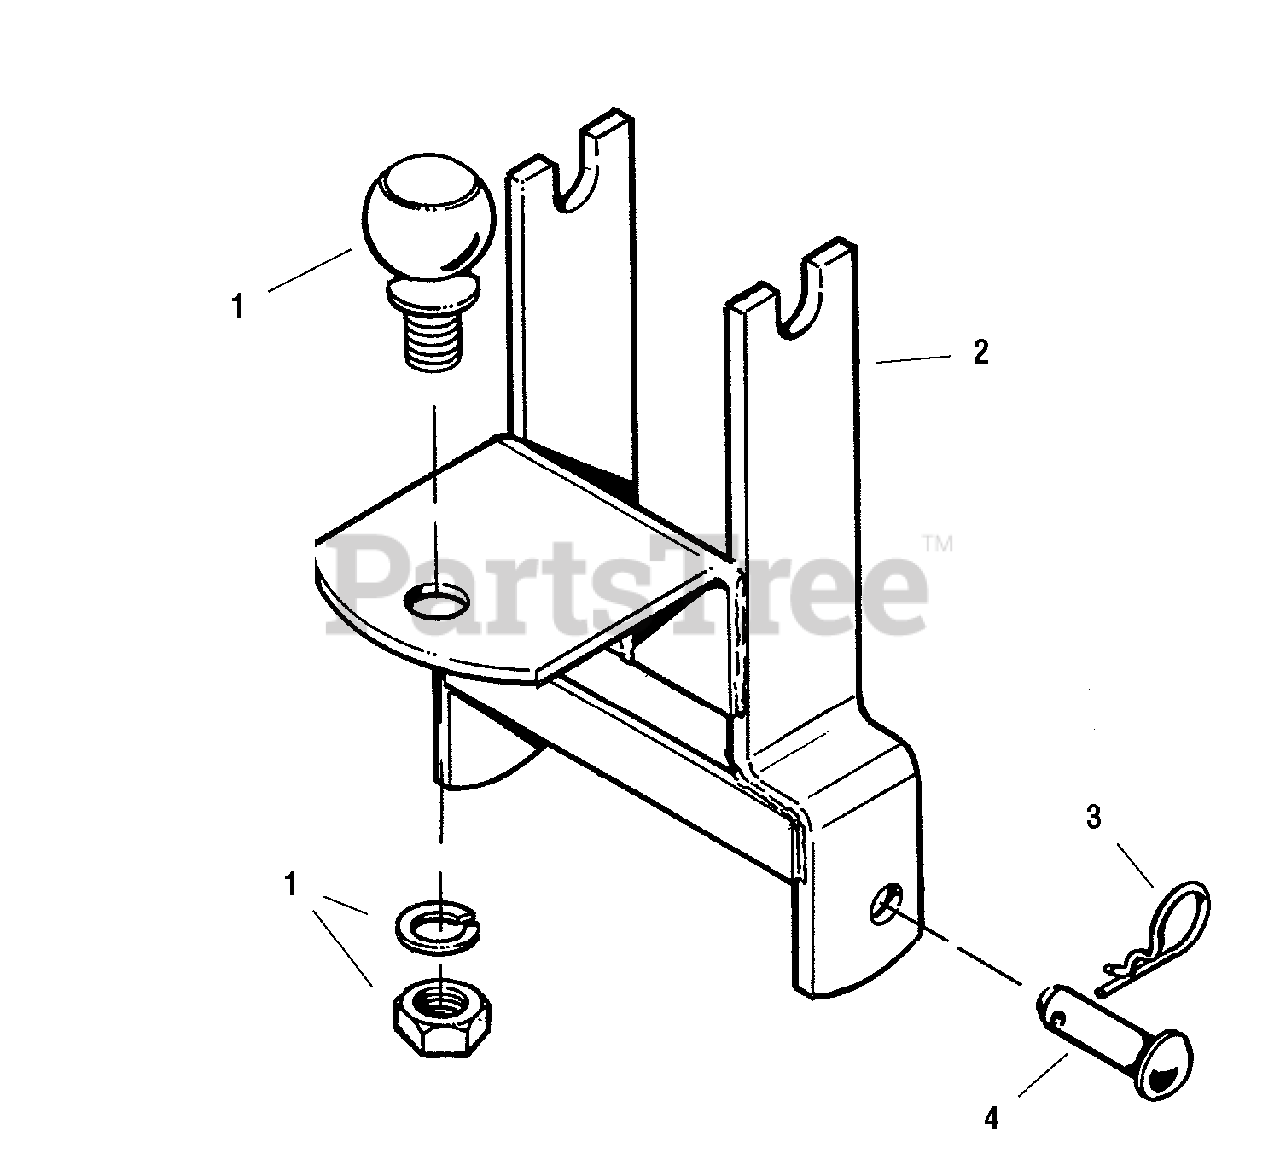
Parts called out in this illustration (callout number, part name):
1	BALL HITCH
2	HITCH ASSEMBLY REAR
3	SPRING CLIP
